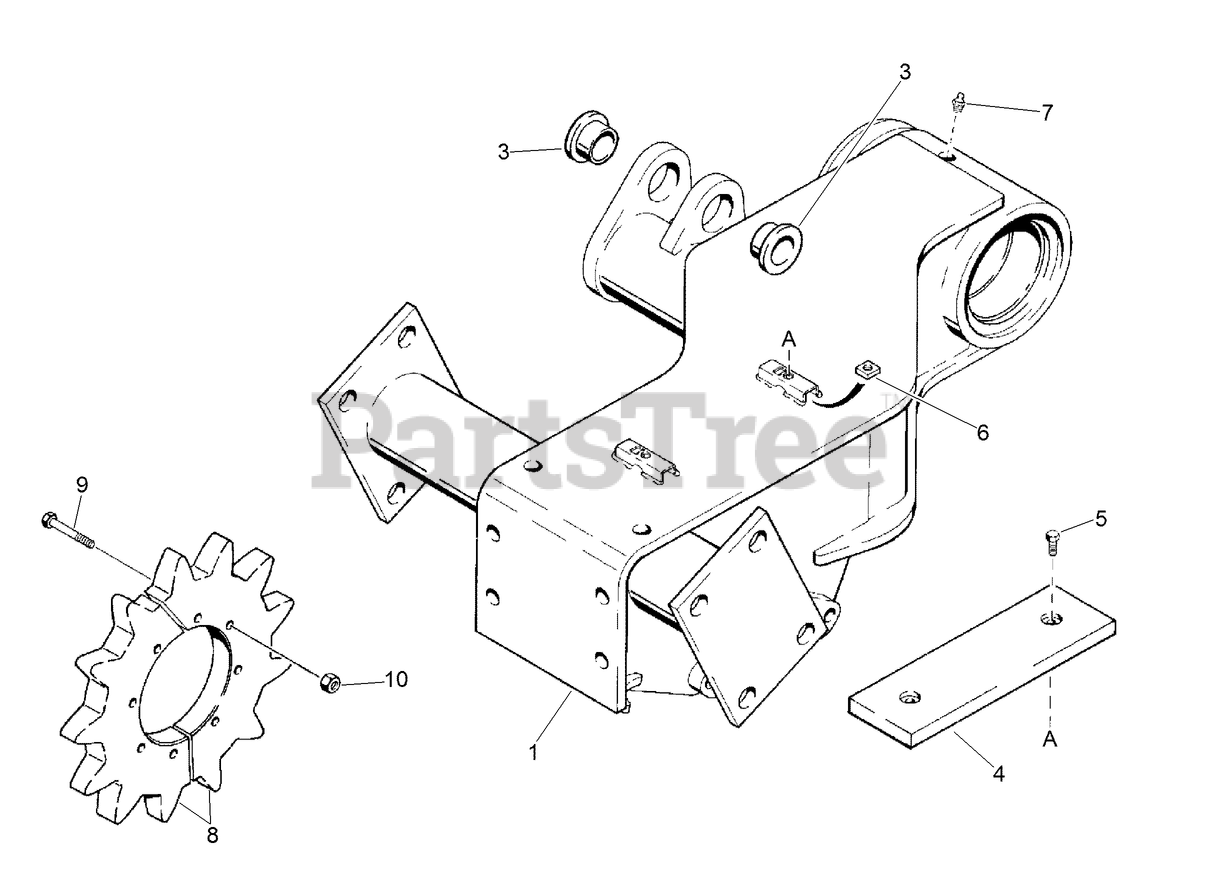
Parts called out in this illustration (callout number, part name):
1	WELDMENT - Boom Attach
3	BUSHING-PIVOT, BUCKET
4	STRIP - Wear, Long
5	SCREW-HH
6	NUT-SQUARE
7	FITTING-Lube 1/4-28 Tpr SAE-LT .54 Long
8	SPROCKET - Split, 311 Chain
8	SPROCKET - Split, 408 Chain
9	SCREW-HH
9	BOLT - 9/16 x 3
10	NUT-HEX
